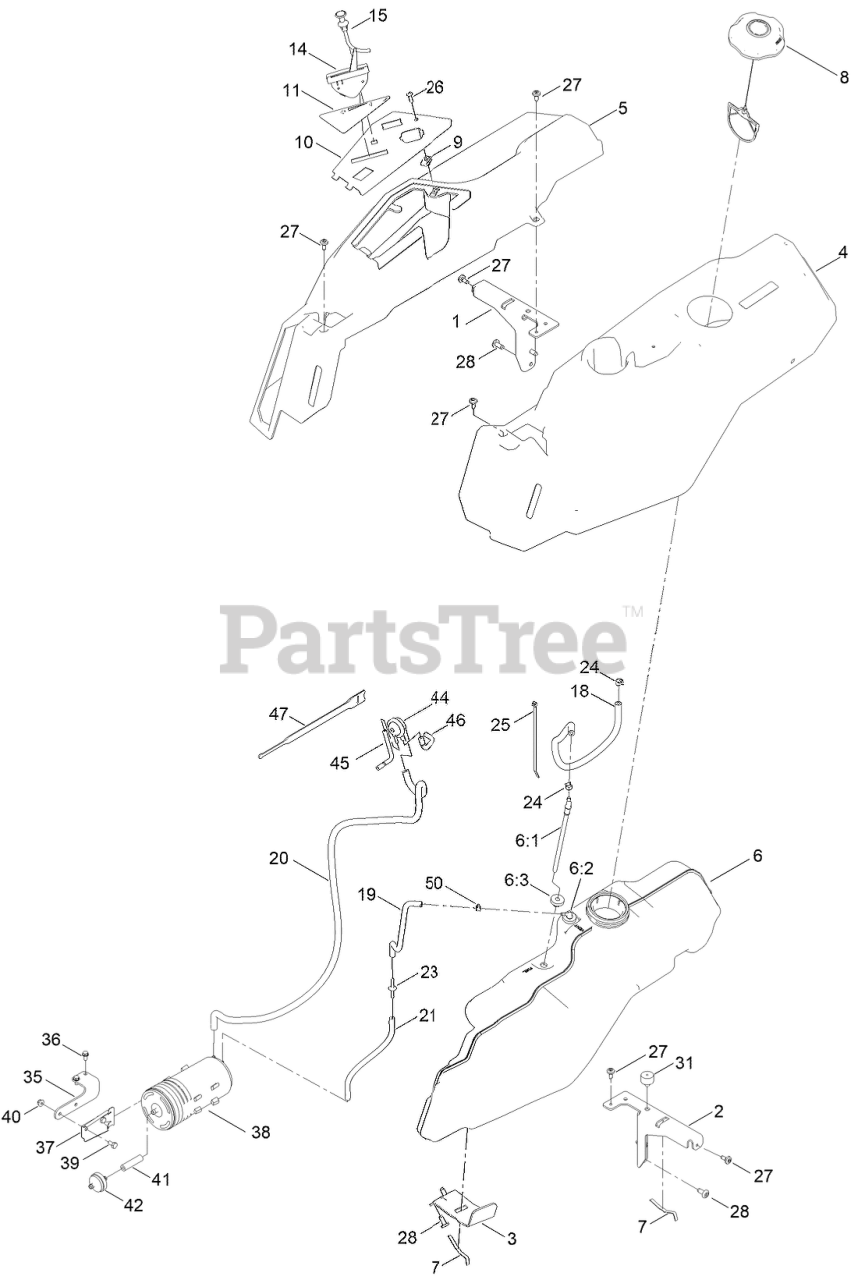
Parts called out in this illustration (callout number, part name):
1	SUPPORT-POD, RH
2	SUPPORT-POD, LH
3	SUPPORT-TANK, FUEL
4	POD-LH
5	POD-RH
6	TANK-FUEL ASM
6:1	CONNECTOR-ELBOW, 90 DEG
6:2	FITTING-ELBOW 90
6:3	BUSHING
7	SPRING
8	CAP-FUEL, RATCHETING
10	PANEL - CONTROL
11	DECAL-PANEL, CONTROL
14	CABLE-THROTTLE
15	CABLE-CHOKE
18	HOSE-FUEL
19	HOSE-FUEL
20	HOSE-FUEL
21	HOSE-FUEL
23	ADAPTER ORIFICE
24	CLAMP-HOSE
25	TIE-CABLE
26	SCREW-PRH
27	SCREW-SHOULDER
31	BUMPER-GROMMET
35	BRACKET-CANISTER, CARBON
36	SCREW-HWH
37	BRACKET-CANISTER, CARBON
38	CANISTER-CARBON, 800CC
39	SCREW-HH
40	NUT-HF
41	HOSE-FUEL
42	FILTER-FUEL, INLINE
44	VALVE-CONTROL, VACUUM
45	HOSE-VENT, FORMED
46	HOSE-VENT, FORMED
47	STRAP-VELCRO, CABLE TIE
50	CLAMP-HOSE
